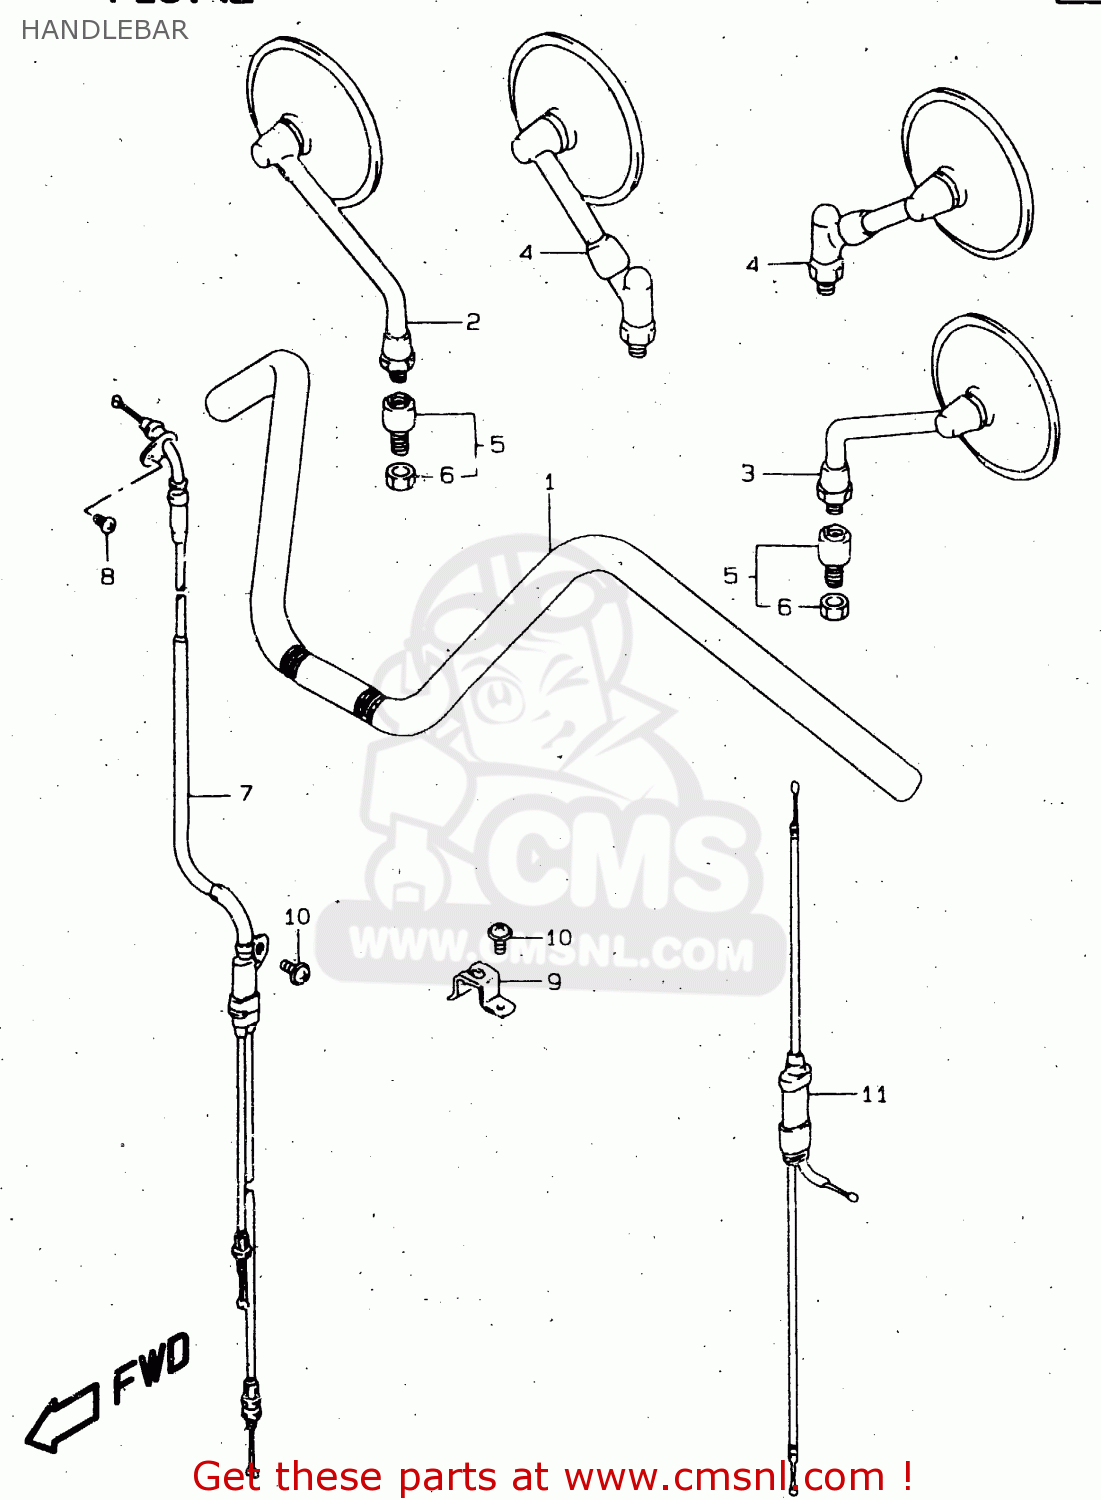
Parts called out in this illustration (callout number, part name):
1	HANDLEBAR
2	MIRROR ASSY RH
3	MIRROR ASSY
4	MIRROR ASSY,RH
5	CUSHION,REAR VIEW MIRROR
6	NUT
7	CABLE ASSY,THROTTLE
8	SCREW
9	CLAMP,THROTTLE CABLE CONNECTOR
10	SCREW
11	CABLE ASSEMBLY,STARTER
